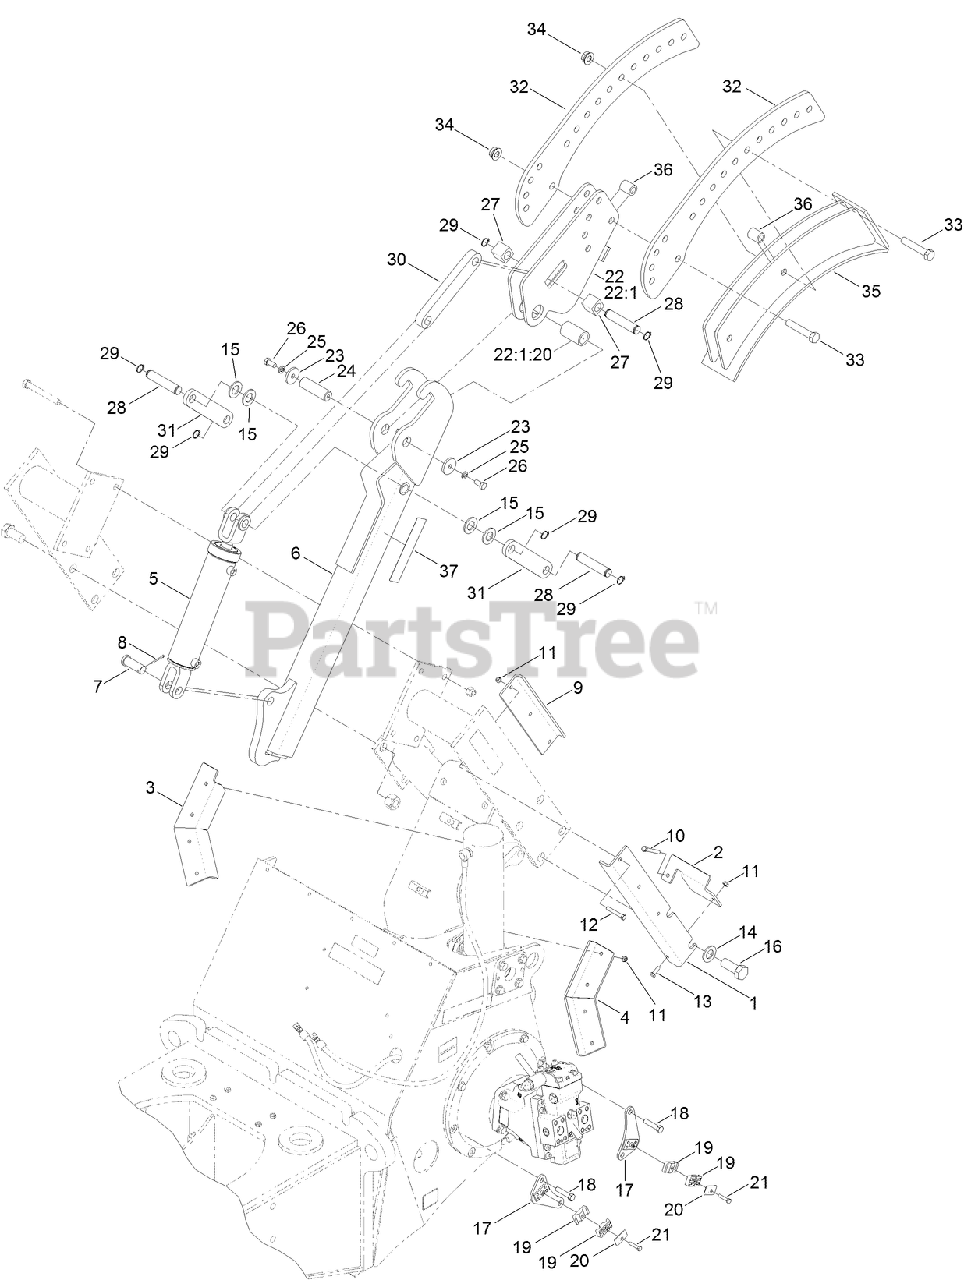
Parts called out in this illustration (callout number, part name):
1	ANGLE-CONDUIT
2	ANGLE-TIE
3	ANGLE-LOWER CONDUIT
4	ANGLE-LOWER CONDUIT
5	CYLINDER-HYDRAULIC
6	TUBE-CRUMBER 4 FT
7	PIN-CLEVIS
8	PIN-COTTER
9	ANGLE-CONDUIT
10	SCREW-HH
11	NUT-HEX
12	SCREW-HH
13	SCREW-HH
17	MOUNT-CLAMP, HOSE
18	SCREW-HH
19	CLAMP-TUBE
20	COVERPLATE
22	PIVOT-CRUMBER
22:1	PIVOT-CRUMBER
22:1:20	TUBE-PIVOT, CRUMBER
23	WASHER-FLAT
24	PIN-PIVOT, CRUMBER PIVOT
25	WASHER-LOCK
26	SCREW-HH
27	BLOCK-SLIDE - SQ. BAR
28	PIN-CYLINDER, ROD
29	RING-RETAINING
30	LINK-CRUMBER PUSH
31	LINK-CRUMBER, STRAIGHT
32	PLATE-CRUMBER CONNECTOR
34	NUT-HEX FLANGE
35	SHOE-CRUMBER - BLADE MOUNT
36	SPACER
37	DECAL-DANGER, ENTANGLEMENT
